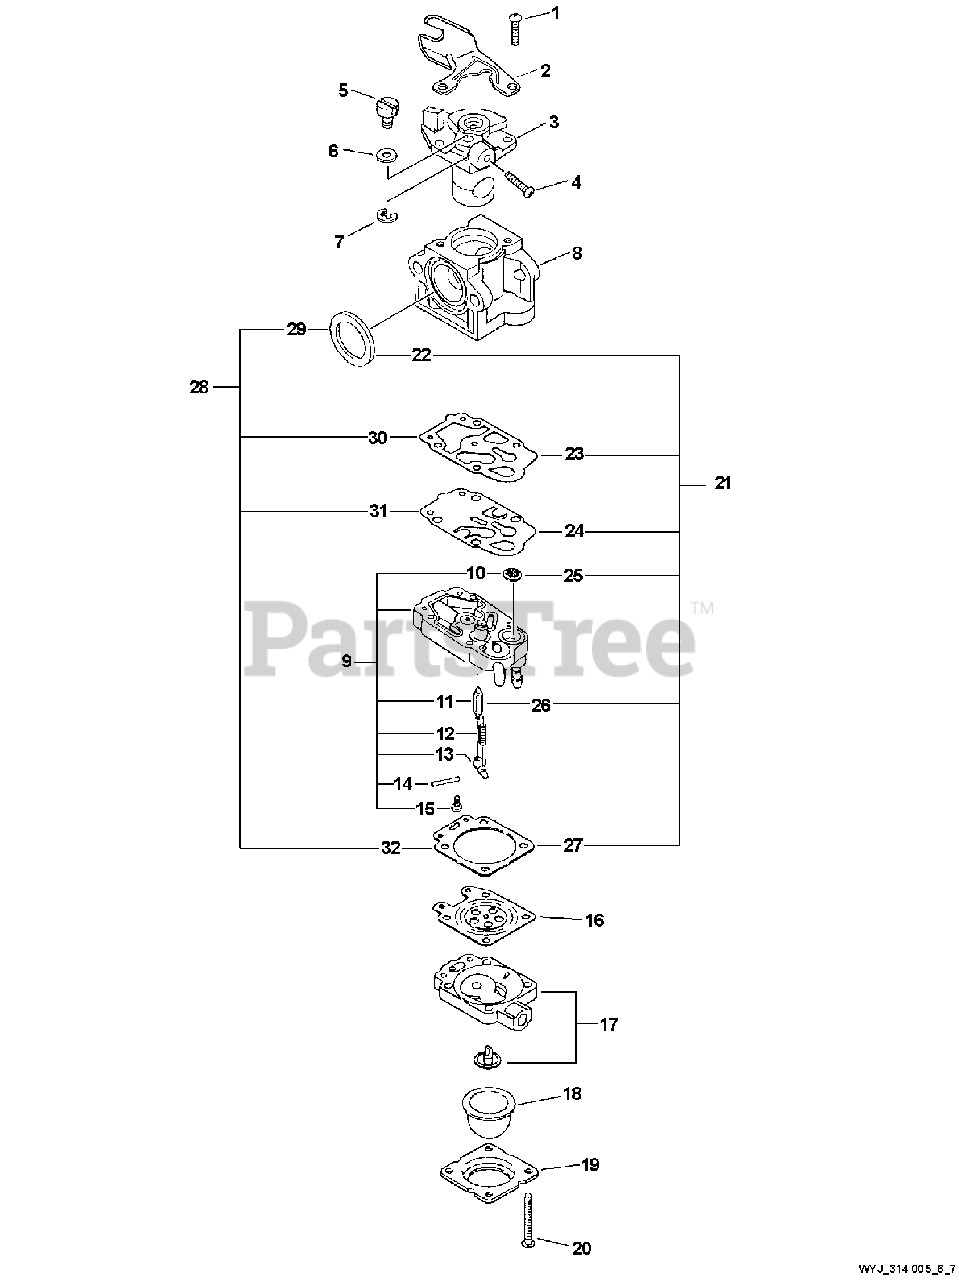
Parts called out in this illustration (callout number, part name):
2	BRACKET, CABLE
3	THROTTLE VALVE ASSY
4	SCREW, IDLE ADJUST
7	RING, RETAINING
8	BODY, CARBURETOR
9	PUMP BODY ASSY
10	STRAINER
11	VALVE, INLET NEEDLE
12	SPRING, METERING LEVER
13	LEVER, METERING
14	PIN, METERING LEVER
15	SCREW, METERING LEVER PIN
16	DIAPHRAGM, METERING
17	PURGE BASE ASSY
18	BULB, PURGE
19	RETAINER, PURGE BULB
20	SCREW, PUMP COVER
21	REPAIR KIT
22	SEAL
23	GASKET, PUMP
24	DIAPHRAGM, PUMP
25	STRAINER
26	VALVE, INLET NEEDLE
27	GASKET, DIAPHRAGM
28	DIAPHRAGM/GASKET KIT
29	SEAL
30	GASKET, PUMP
31	DIAPHRAGM, PUMP
32	GASKET, DIAPHRAGM
